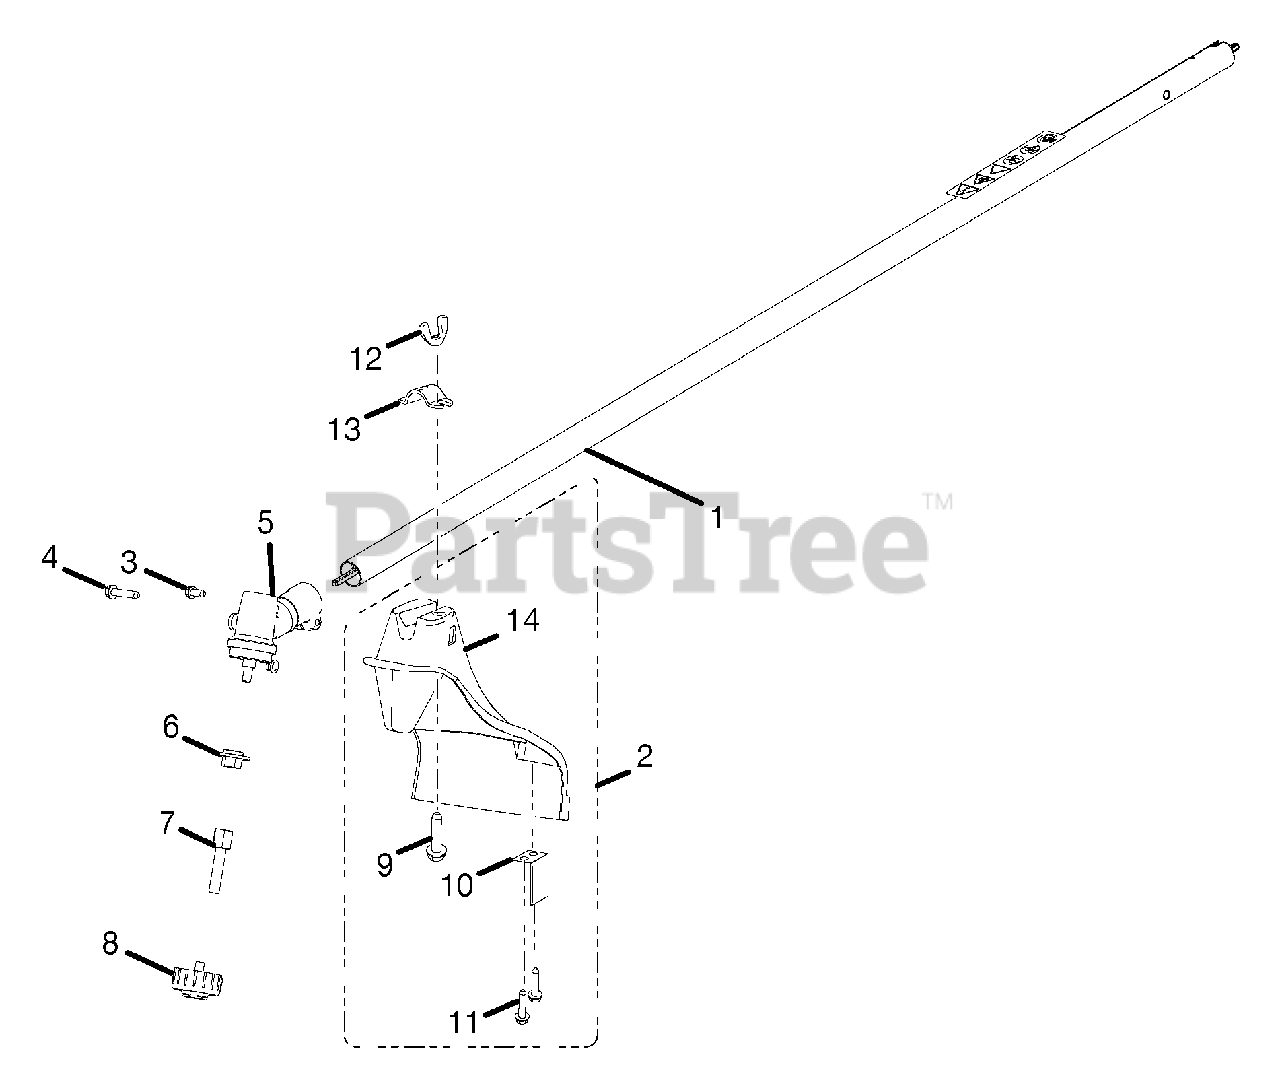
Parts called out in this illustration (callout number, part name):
1	STRAIGHT SHAFT ASSEMBLY
2	GRASS SHIELD ASSEMBLY
3	SCREW (10-24 x 5/8 in)
4	SCREW (10-24 x 1-1/4 in.)
5	GEAR HEAD
6	WASHER
7	SHAFT ADAPTER
8	SPOOL RETAINER (LH)
9	SCREW, SQUARE HEAD
10	CUT OFF BLADE
11	SCREW
12	WING NUT
13	SHIELD CLAMP
14	GRASS SHIELD
